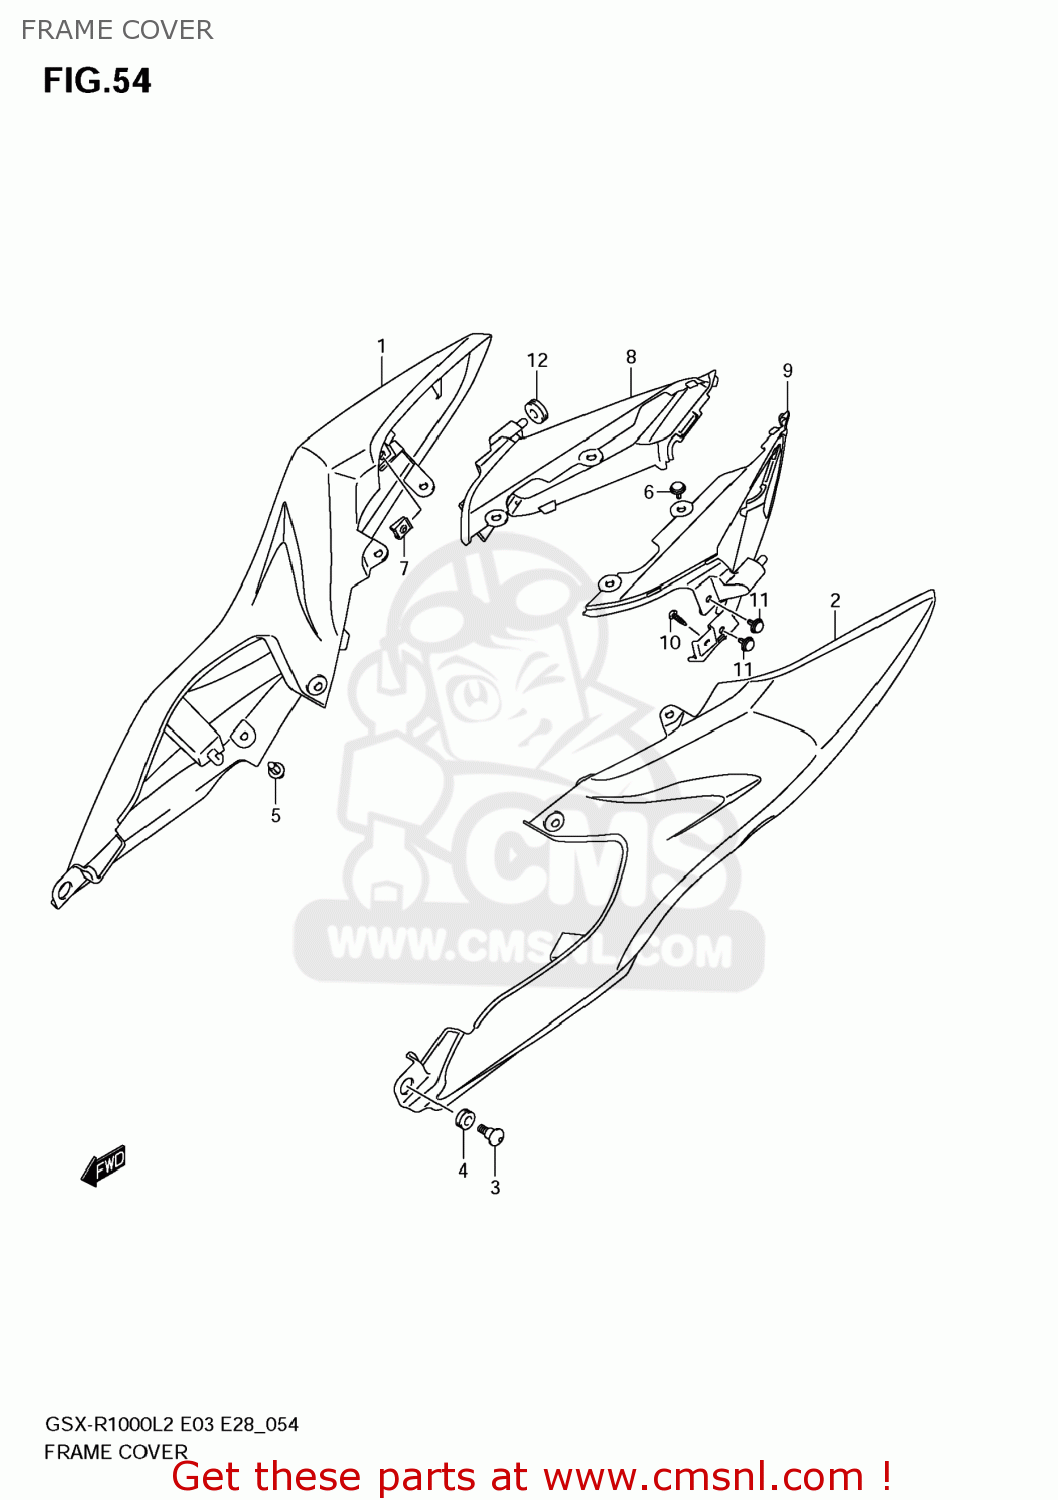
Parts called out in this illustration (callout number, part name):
1	COVER,FRAME,R(WHITE)
2	COVER,FRAME,L(WHITE)
3	SCREW,SIDE COVER LWR,R
4	CUSHION
5	CLIP(BLACK)
6	CLIP
7	NUT
8	COVER,FRAME RR,R
9	COVER,FRAME RR,L
10	SCREW
11	CLIP
12	CUSHION
